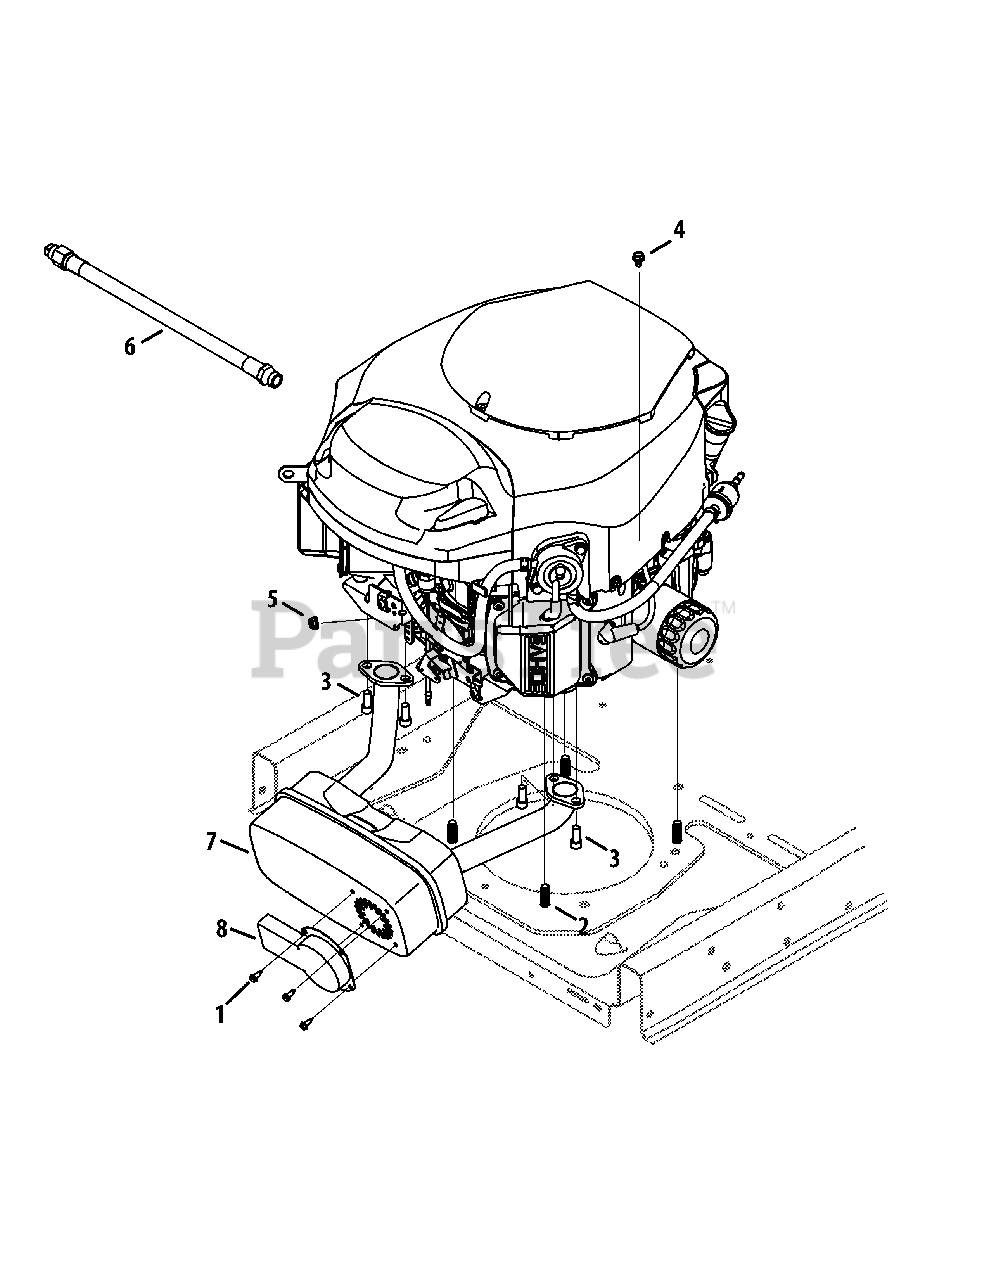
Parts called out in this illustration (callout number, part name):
1	Hex Washer Screw, #8-18 x .500
2	Hex Washer Screw, 3/8-16 x 1.00
3	Socket Head Screw, 5/16-18 x .750
4	Hex Washer Screw, 1/4-20 x .625
5	Flange Lock Nut, 1/4-20
6	Oil Drain Hose
7	Twin Muffler
8	Deflector, Muffler, Long
